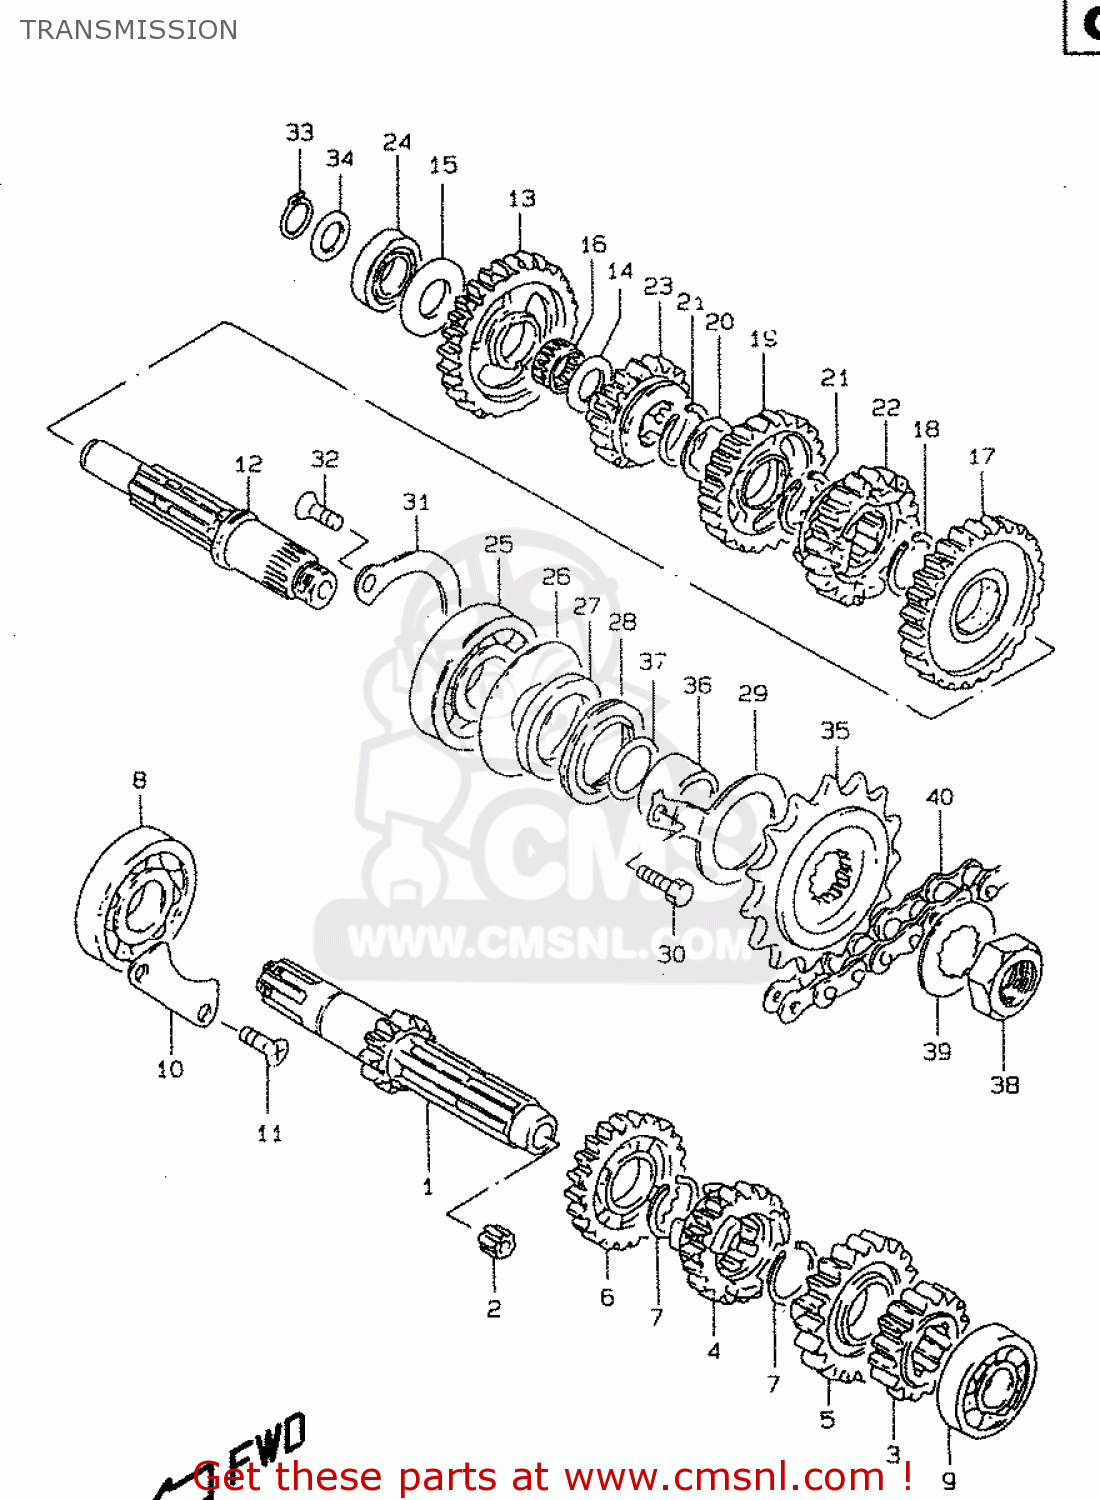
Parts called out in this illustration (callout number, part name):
1	SHAFT,COUNTER (NT:11)
2	BUSH
3	GEAR,2ND DRIVE(NT:16)
4	GEAR,3RD DRIVE(NT:19)
5	GEAR,4TH DRIVE(NT:20)
6	GEAR,FIFTH DRIVE (NT:22)
7	CIRCLIP
8	BEARING(22X56X16)
9	BEARING(17X40X12)
10	RETAINER,CNTR SHAFT BEARING
11	SCREW
12	SHAFT,DRIVE
13	GEAR,1ST DRIVEN(NT:29)
14	SHIM(17X28X1)
15	WASHER
16	BEARING(17X21X9.8)
17	GEAR,2ND DRIVEN(NT:27)
18	CIRCLIP
19	GEAR,3RD DRIVEN(NT:24)
20	WASHER,LOCK
21	CIRCLIP
22	GEAR,4TH DRIVEN(NT:20)
23	GEAR,5TH DRIVEN(NT:18)
24	BEARING(17X36X12)
25	BEARING(22X56X16)
26	WASHER(35X55X1)
27	OIL SEAL (30X43X5)
28	OIL SEAL (30X43X7)
29	RETAINER,DRIVE SHAFT OIL SEAL
30	BOLT
31	RETAINER,DRIVE SHAFT BEARING
32	SCREW
33	CIRCLIP,17MM
34	SHIM(17X24X1)
35	SPROCKET,ENGINE(NT:15)
36	SPACER
37	O RING(D:2.5,ID:21)
38	NUT
39	WASHER,LOCK
40	CHAIN(DID520VC5,110LE)
